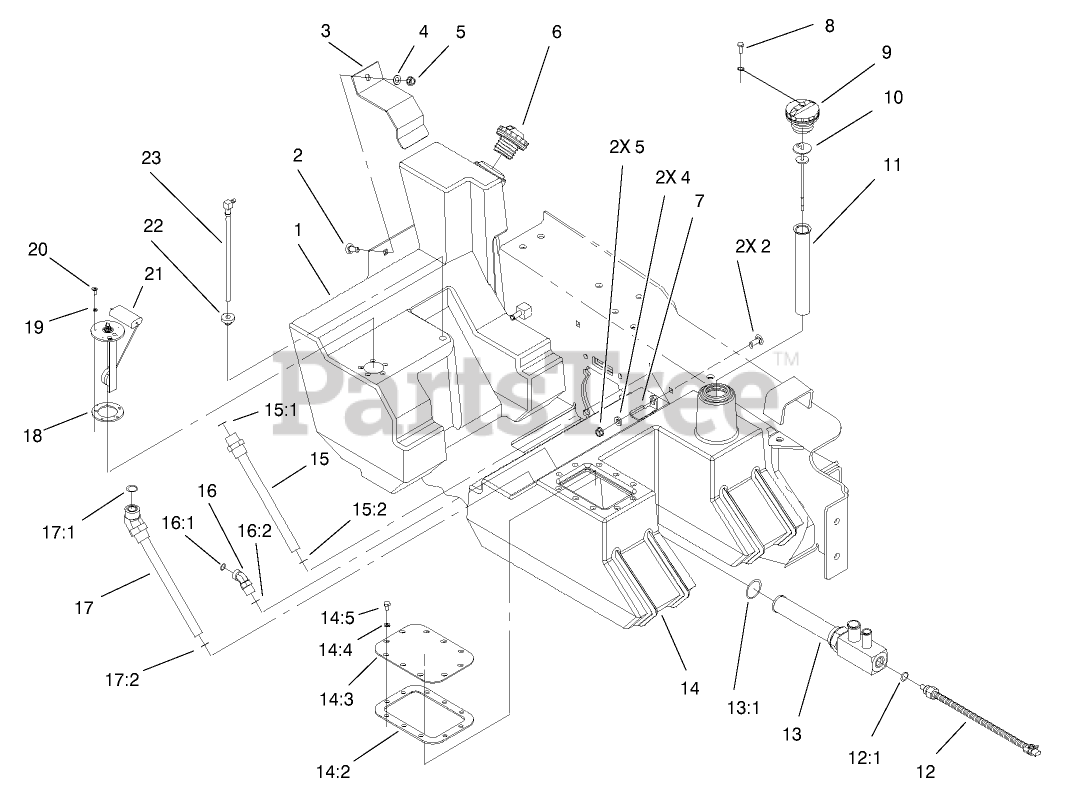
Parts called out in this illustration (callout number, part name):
1	TANK-FUEL
2	SCREW-CARR
3	CLAMP-TANK, FUEL
4	WASHER-FLAT
5	NUT-LOCK, NI
6	CAP-FUEL
7	CLAMP-TANK, HYDRAULIC OIL
8	SCREW-HH
9	CAP-OIL, HYD
10	DIPSTICK ASM
11	SCREEN-FILLER
12	SENSOR-TEMPERATURE
12:1	O-RING
13	OUTLET FITTING ASM
13:1	O-RING
14	HYDRAULIC TANK ASM
14:2	GASKET-COVER, ACCESS
14:3	COVER-ACCESS
14:4	WASHER-LOCK
14:5	SCREW-HH
15	RETURN FITTING ASM
15:1	O-RING
15:2	O-RING
16	FITTING-HYD, 45 DEG
16:1	O-RING
16:2	O-RING
17	RETURN FITTING ASM
17:1	O-RING
17:2	O-RING
18	GASKET-SENDER, FUEL
19	WASHER-LOCK
20	SCREW-PPH
21	SENDER-FUEL
22	BUSHING
23	PIPE-STAND
